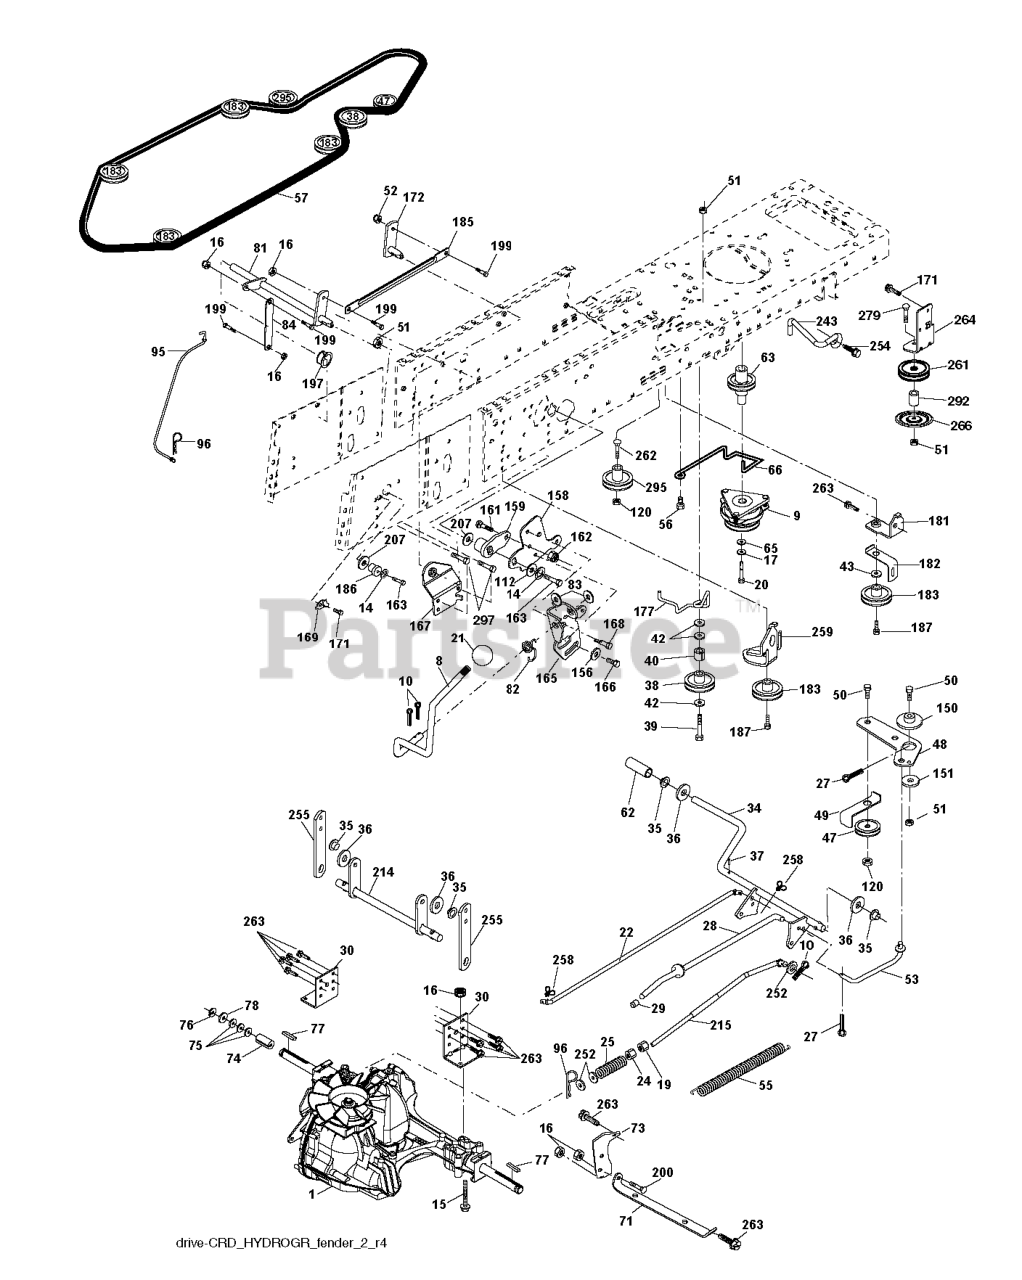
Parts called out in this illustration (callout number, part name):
8	ROD SHIFT FENDER ADJUST LT
9	CLUTCH.ELECTRIC.OGURA.EURO.
10	PIN COTTER
14	LOCKWASHER
15	BOLT HEX 5/16-18 GR 5
16	NUT.71038.31-18.HEX.NYLOCK
19	NUT
20	BOLT HEX 7/16-20X4-1/4"
21	KNOB.DUCKHEAD.1/2
22	ROD
24	NUT
25	SPRING BRAKE ROD
27	COTTER PIN
28	ROD, PARKING BRAKE
29	PLUNGER CAP
30	BRKT, TRNSXLE MNT 20"
34	SHAFT, FOOT PEDAL
35	BEARING.NYLON
37	DRIVE PIN
38	PULLEY.FLAT
42	WASHER
47	IDLER PULLEY
48	BELLCRANK, CLUTCH
49	RETAIN BELT
50	BOLT.3/8-16X1.50
52	LOCKNUT
53	LINK.CLUTCH.7.66.2005
55	SPRING, RETURN LT
56	SCREW.3/8-16
57	V-BELT 113"
62	PEDAL COVER T
63	PULLEY.ENGINE.CVX.LT
65	LOCKWASHER
66	KEEPER BELT ENGINE
71	STRAP TORQUE LH HYDRO
73	STRAP TORQUE RH HYDRO
74	SPACER AXLE
77	SQUARE KEY
81	ASM.CROSS.SHAFT.REAR.CRD.0510
82	SHIFT SPRING
83	WASHER
84	LINK.PNT.TRANSAXLE.0510.CRD
95	LINK
96	RETAINER M
120	NUT LOCK FLG 3/8-16 UNC
150	BUSHING.BELLCRANK.GRD.DR
151	WASHER 12/32X2X10GA
156	WASHER.SRRTD.5/16
158	BRACKET
159	RB HUB.SHIFT
161	BOLT
162	NUT.CROWNLOCK.1/4
165	RP BRACKET
166	CAPSCREW.HXHD.FLG.5/16-18X.625
167	BRACKET.SUPT.SHIFT.CRD
168	BOLT.SHOULDER.5/16-18X
169	PLATE.FASTENING.CROSS.SHAFT
172	LINK
181	BRACKET
182	BELT GUIDE
183	PULLEY.V-IDLER.
185	LINK
186	HUB.TAPERED.ROUND.CRD
187	BOLT.5/16-18X1.25
197	NYLINER SNAP 5/8" ID
199	BOLT SHOULDER 5/16-18 UNC
207	WASHER NYL
214	LEVER
215	ROD
243	BRACKET, ANTI-ROTATION
252	WASHER
254	SCREW 3/8-16X1
255	SHAFT
258	CLIP RETAINER
259	BRACKET
261	FLAT IDLER PULLEY
263	SCREW, 3/8-16X3/4
264	BRACKET.IDLER
266	PROTECTOR
292	SPACER
295	PULLEY IDLER COMPOSITE
297	SCREW LT.3/8-46X5/8
